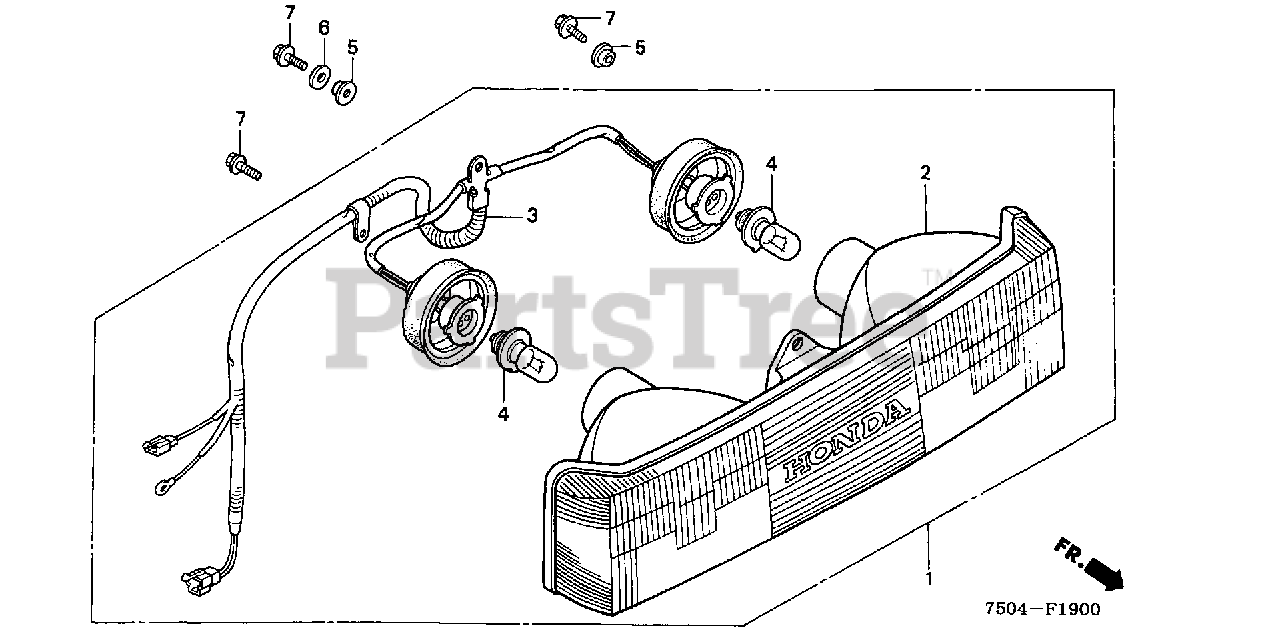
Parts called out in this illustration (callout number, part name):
1	HEADLIGHT ASSY.
2	HEADLIGHT UNIT (NOT AVAILABLE)
3	SOCKET, HEADLIGHT
4	BULB, HEADLIGHT (12V15W) (STANLEY)
5	COLLAR, COWL SETTING (LOWER)
6	WASHER, PLAIN (6MM)
7	BOLT, FLANGE (6X16)
